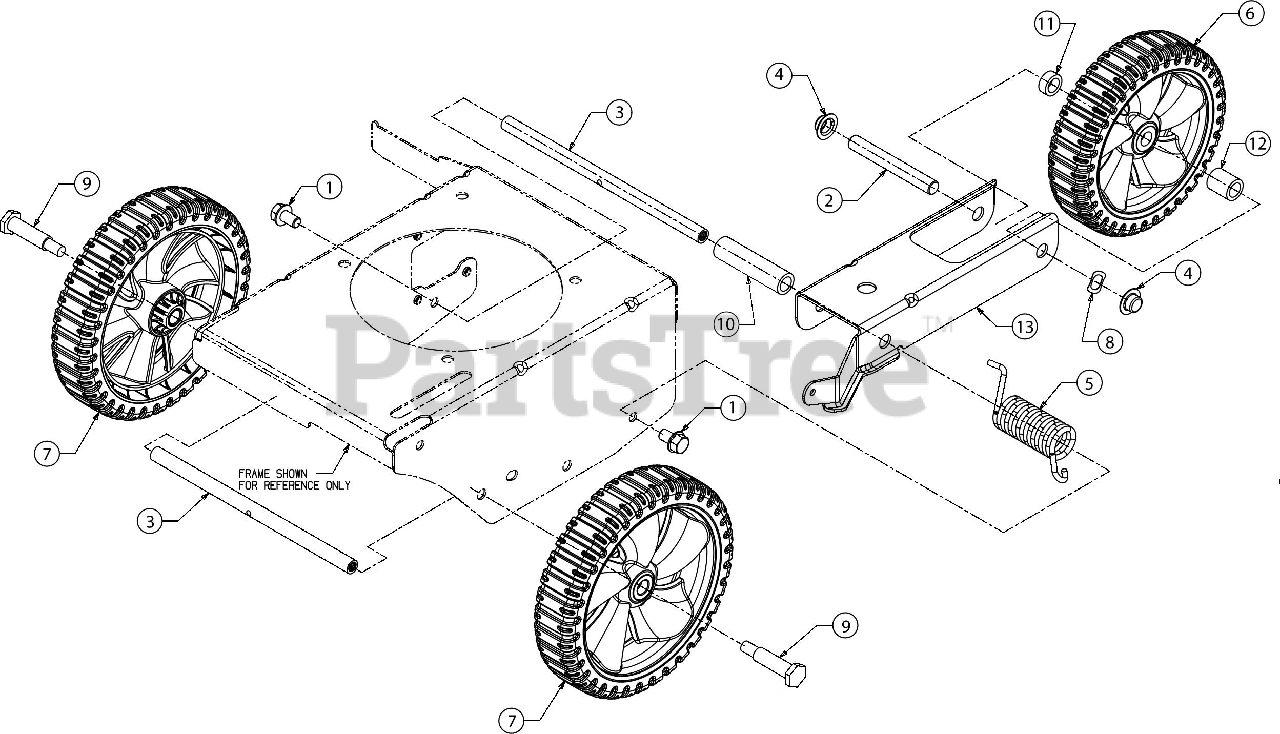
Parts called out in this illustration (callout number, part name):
1	SCREW 3/8-16X.625 GR 5
2	AXLE SHAFT
3	SPACER .50 X 9.25
4	PUSH CAP
5	TORSION SPRING
6	WHEEL-7 X 1.8
7	WHEEL-8 X 1.8
8	WAVE WASHER
9	SHOULDER BOLT .498 X 1.635:3/8-16
10	SPACER
11	SPACER
12	SPACER
13	WHEEL BRACKET
